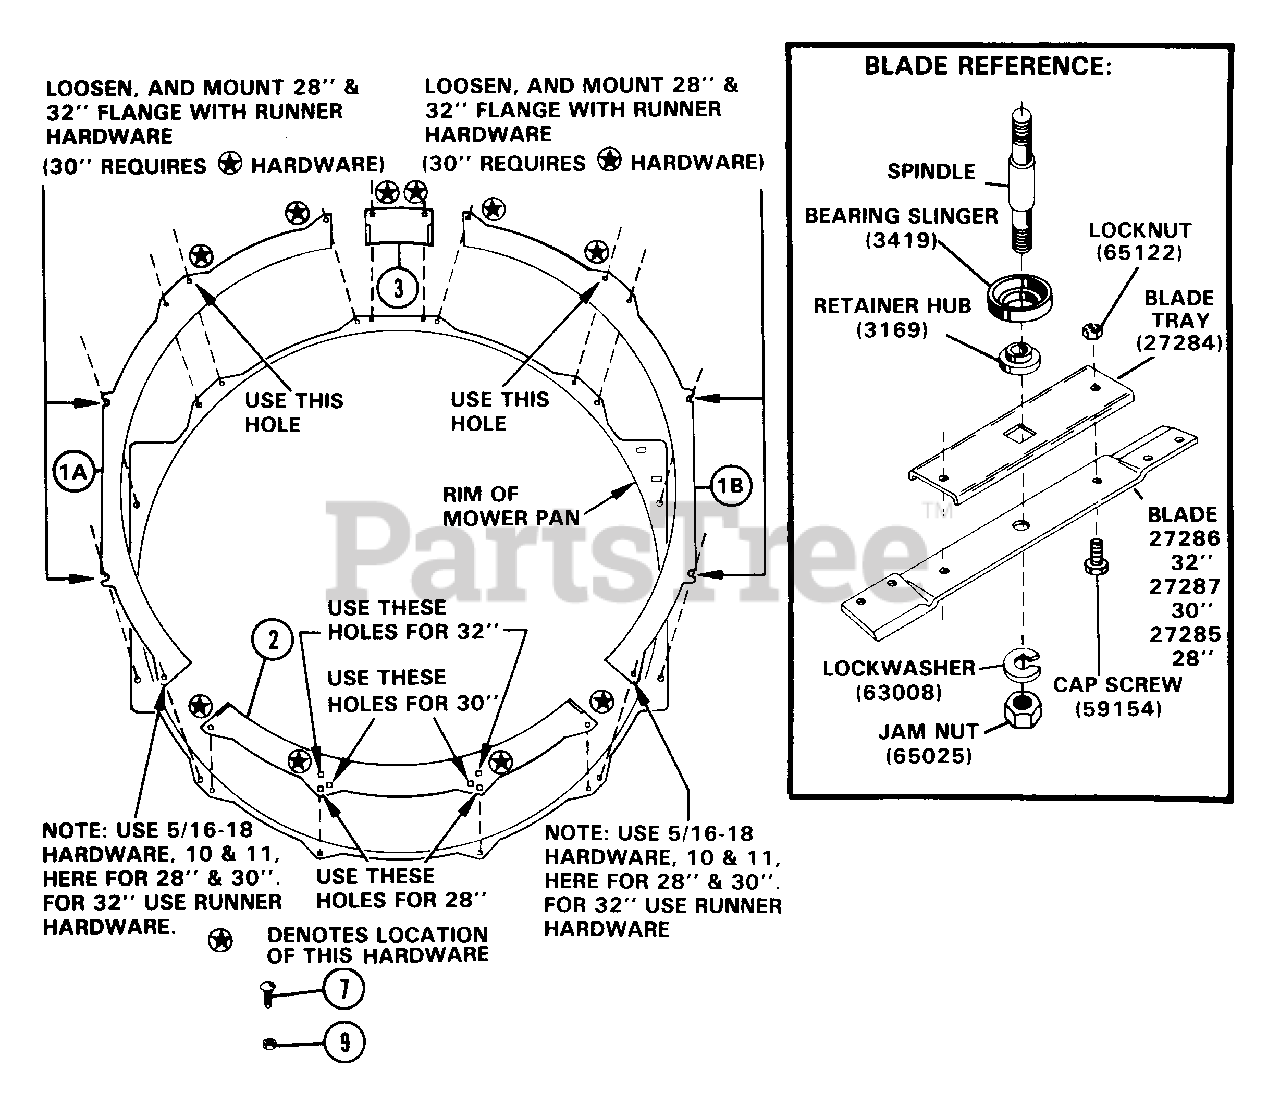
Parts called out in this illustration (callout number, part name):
1A	30 IN FLANGE R H
1B	30 IN FLANGE L H
2	BACK FLANGE
3	FRONT CLAMP
7	BLT-RDHDSQNK .25-20X.62 PL
9	NUT-LK-CTR .250-20 PL
10	BLT-RDHDSQNK .312-18X.62SHTPL
11	NUT-LK .312-18 GR A PL
